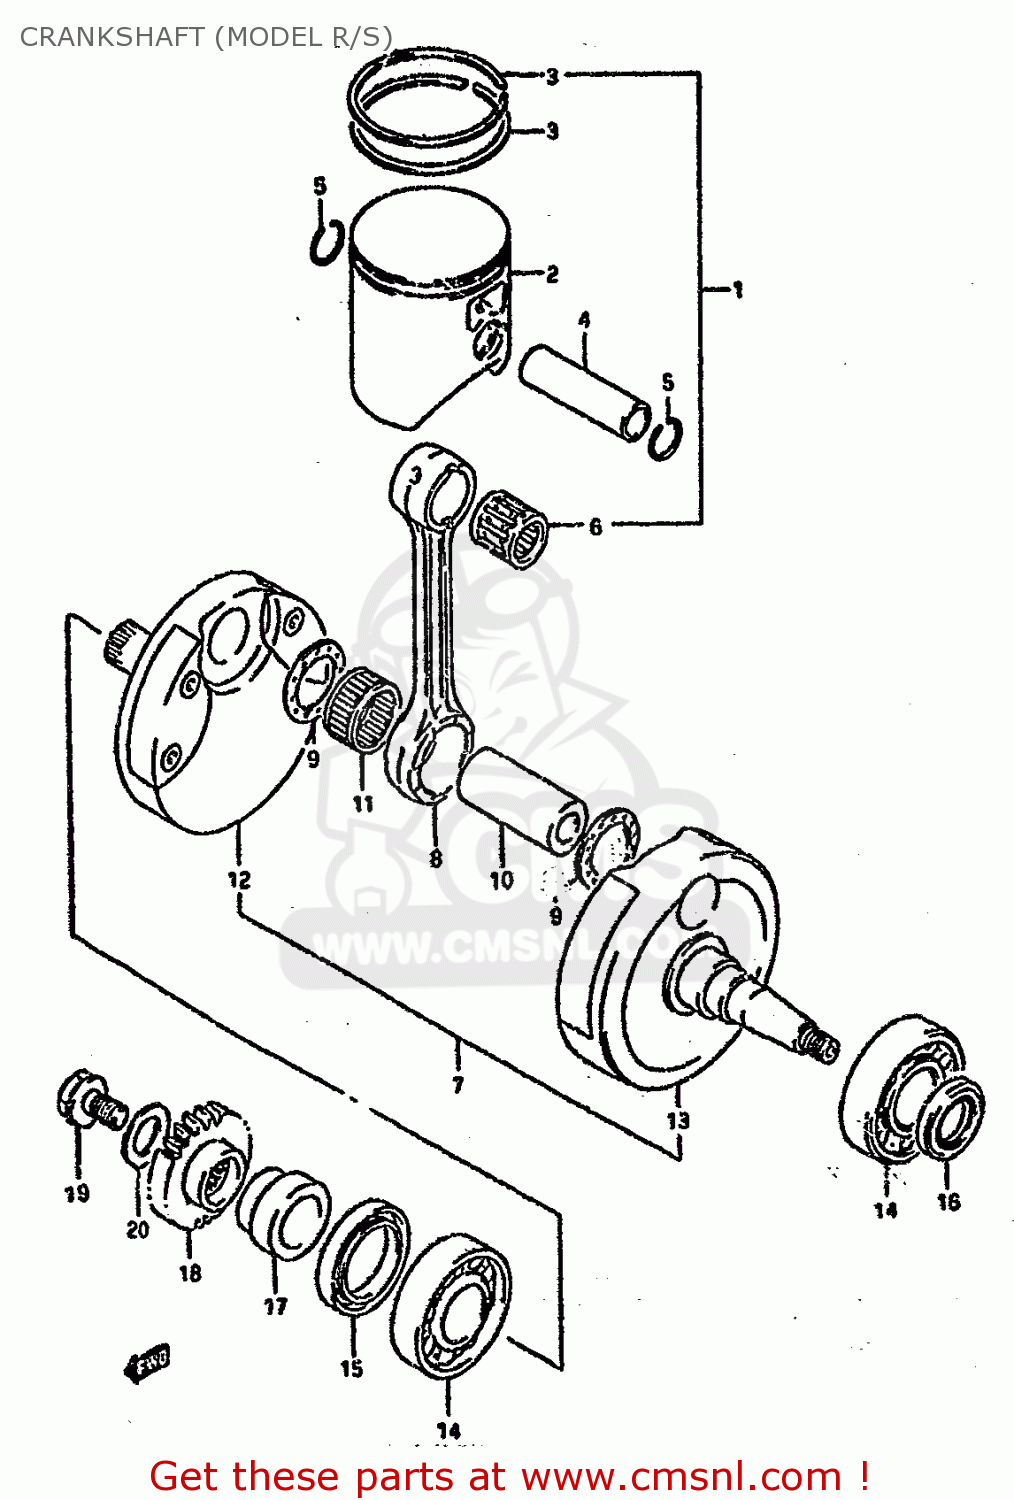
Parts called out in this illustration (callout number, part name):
1	PISTON KIT
2	PISTON COMP
3	RING,PISTON
4	PIN,PISTON
5	CIRCLIP,PISTON PIN
6	BEARING(18X23X22)
7	CRANKSHAFT ASSY
8	ROD,CONNECTING
9	WASHER(24X38.5X1.5)
10	PIN,CRANK
11	BEARING(24X30X20)
12	CRANKSHAFT,R
13	CRANKSHAFT,L
14	BEARING(28X68X18)
15	SEAL,OIL(38X52X8)
16	SEAL,OIL(20X37X6)
17	SPACER,PRIMARY DRIVE GEAR
18	GEAR,PRIMARY DRIVE (NT:
19	BOLT,PRIMARY DRIVE GEAR
20	WASHER
